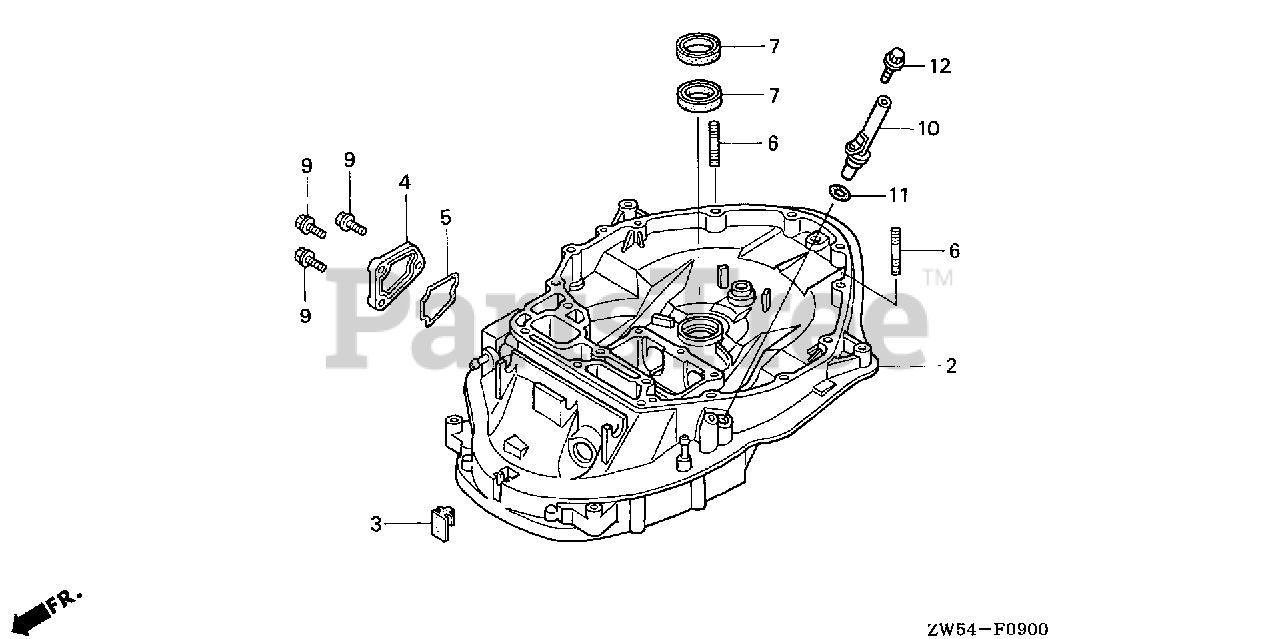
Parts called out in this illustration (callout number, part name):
2	CASE, MOUNT *NH8* (DARK GRAY)
3	RUBBER, MOUNT CASE SEAL
4	COVER, MOUNT CASE *NH8* (DARK GRAY)
5	GASKET, MOUNT CASE COVER
6	BOLT, STUD (10X35)
7	SEAL, WATER (22X35X7)
9	BOLT, FLANGE (6X20)
10	PIPE, OIL LEVEL
11	O-RING (11.5X3.5)
12	BOLT, FLANGE (6X12)
